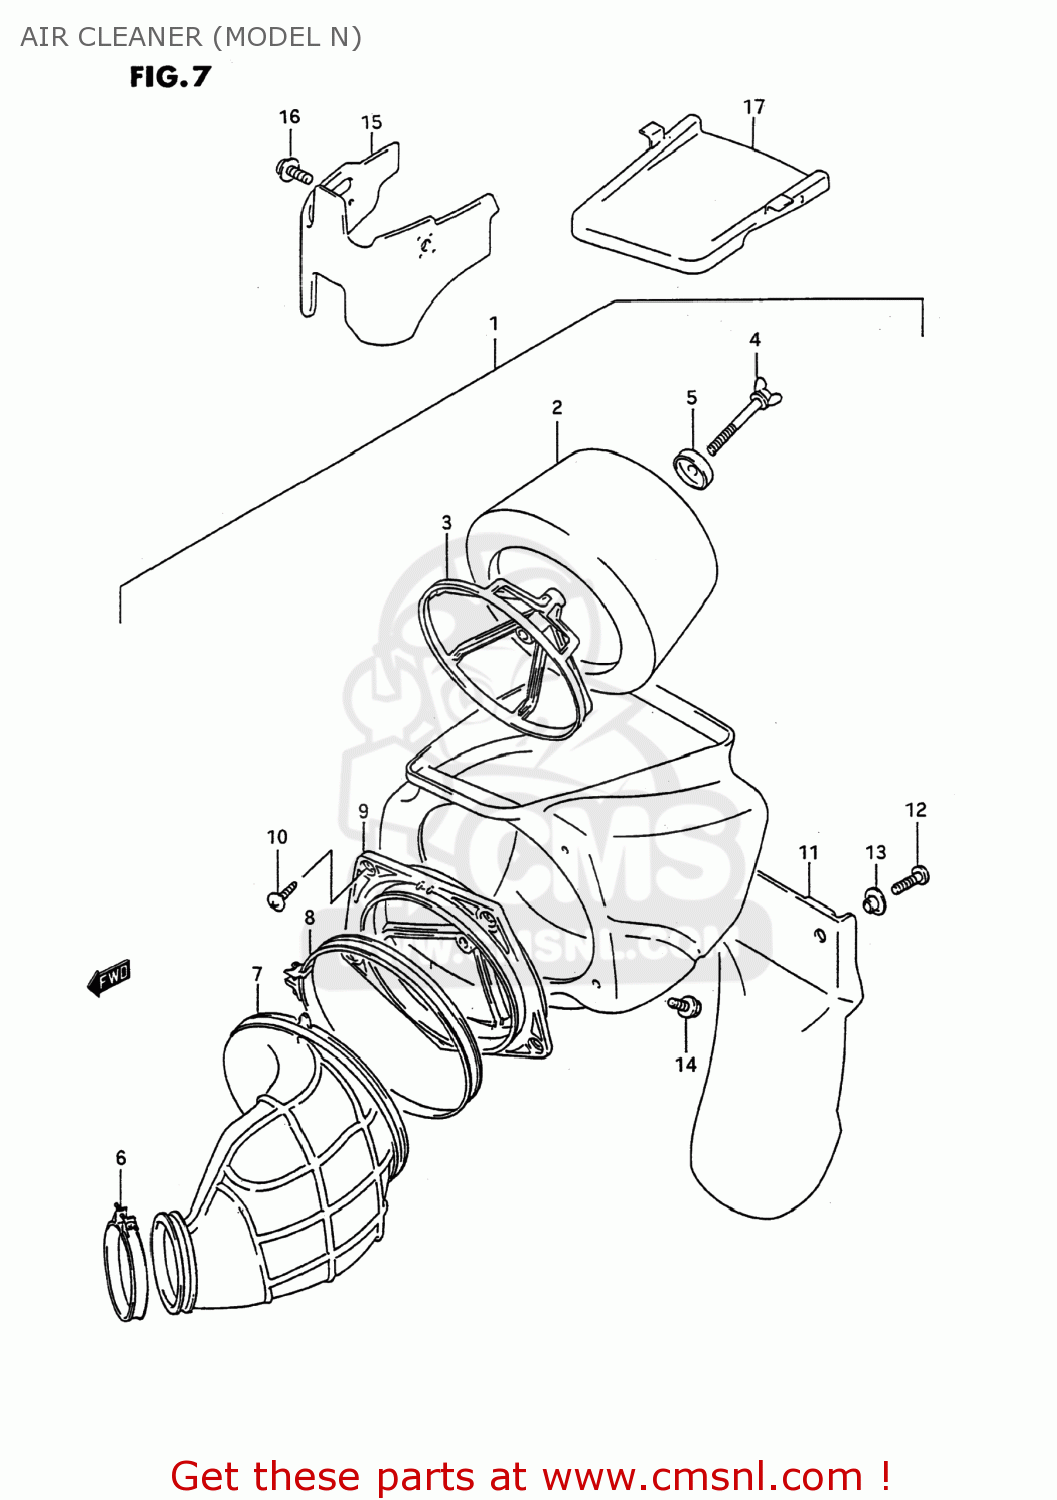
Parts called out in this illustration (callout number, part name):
1	CLEANER ASSEMBLY,AIR
2	FILTER
3	HOLDER,FILTER
4	BOLT,WING
5	WASHER,AIR CLEANER
6	CLAMP
7	TUBE,OUTLET
8	CLAMP
9	HOLDER,FILTER
10	SCREW
11	GUARD,MUD
12	SCREW
13	COLLAR
14	BOLT 6X20
15	GUARD,MUD
16	SCREW(6X12)
17	CAP,AIR CLEANER
